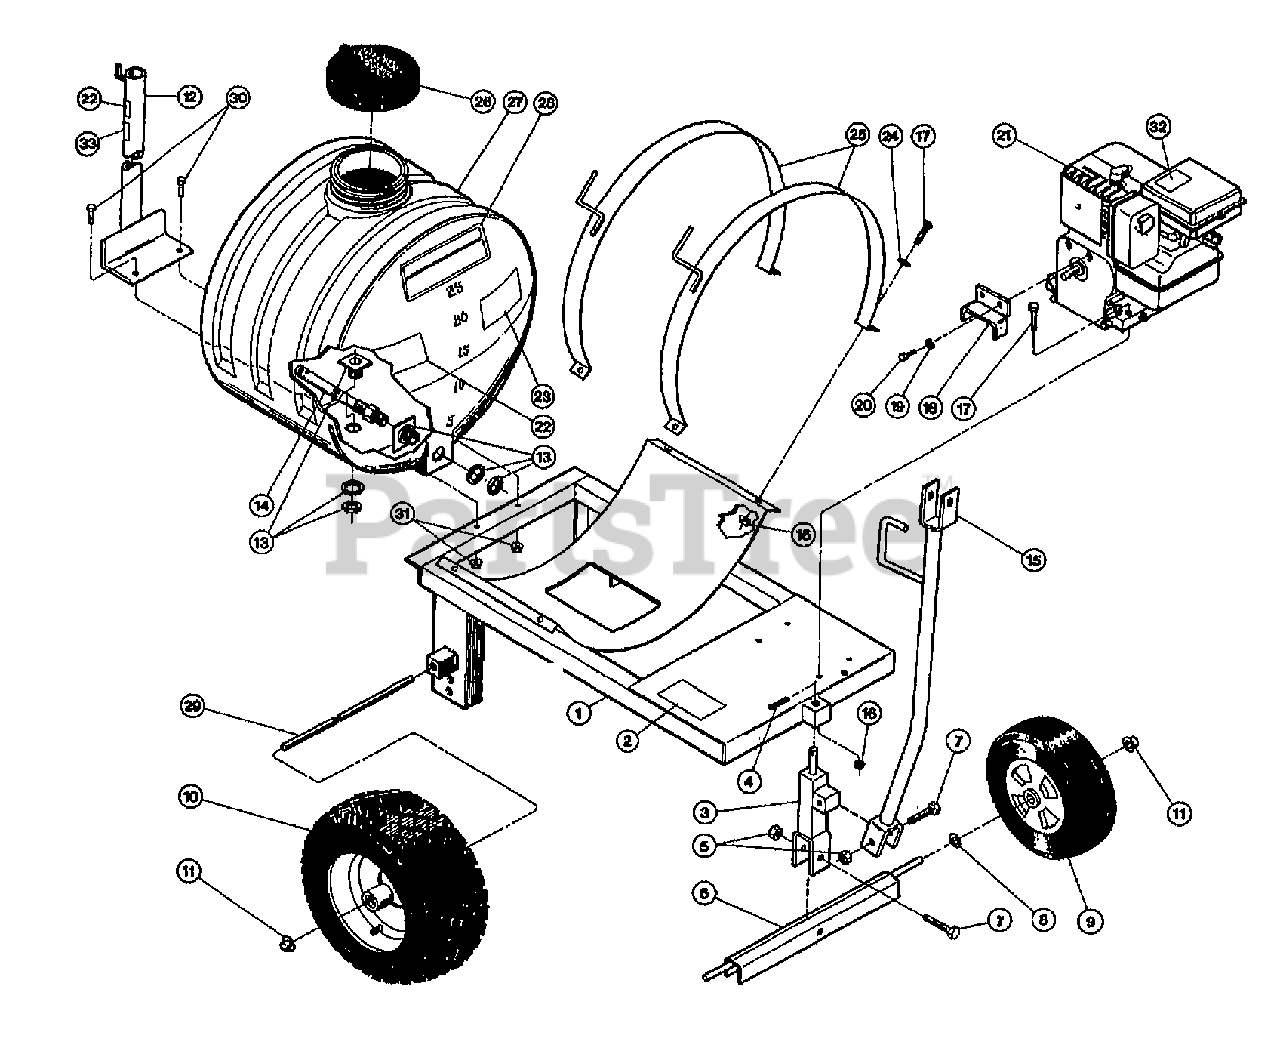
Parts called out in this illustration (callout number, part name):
1	ASSM-UNDERCARRIAGE W21401501
2	DECAL-SAVE
3	ASSM-AXLE PIVOT FRONT
4	PIN-COTTER .120X1.25 ZP
6	ASSM-FRONT AXLE SPRAYER
7	SCR-HH 5/8-11X2.25 G5 ZP
8	WASHER-1.75X.625X.11
9	ASSM-TIRE/WHEEL 11592
10	WHEEL & TIRE ASSY.
11	NUT-PUSH 5/8
12	MAST-BOOM*ALIAS*1985814
13	ASSM-BULK HEAD W21254002
14	AGITATOR-JET W33710019
15	HANDLE-TOW BAR
16	NUT-HFLK 5/16-18 ZP
17	SCR-HH 5/16-18X1.5 G5 ZP
18	COVER-DRIVESHAFT SPRAYER
19	WASHER-LK .312 ZP
20	SCR-GRD 5 W02050502FP
21	ENGINE, 3HP BRIGGS & STRATTON #80232
22	DECAL-DANGER AVOID W2045146
23	DECAL-ENG SPEED W2045149
24	WASHER-FLAT 5/16 SAE
25	TANK-UP CRDL W/HOSE HGRS
26	CAP-TANK W21254503
27	ASSM-TANK 25 GAL W/DECALS
28	DECAL-25GAL SPRAY W2045165
29	AXLE-REAR W2000109B
30	SCR-HH 5/16-18X1.0 G5 ZP
31	NUT-HFLK 5/16-18 ZP
32	DECAL-HOT SURFACE
33	DECAL-40PSI CAUTION W2045147
